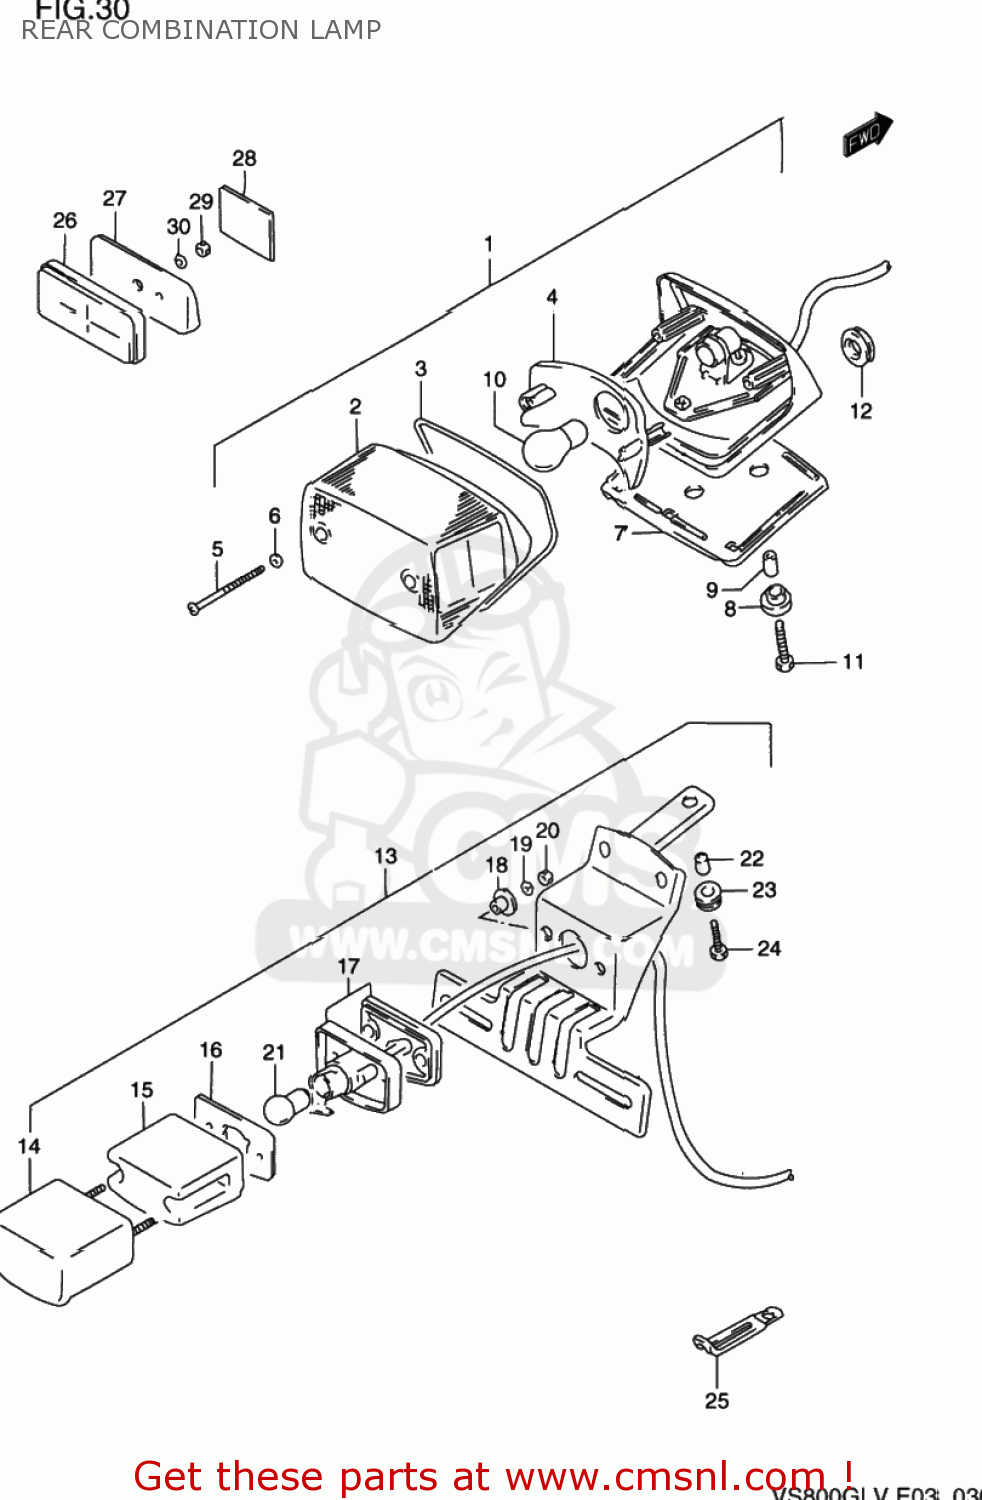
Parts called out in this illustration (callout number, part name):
1	LAMP ASSY,RR COMBINATION
2	LENS
3	GASKET (NAS)
4	REFLECTOR
5	SCREW
6	GASKET (NAS)
7	CUSHION
8	CUSHION
9	SPACER
10	BULB(12V21/5W,BF141-49642A)
11	BOLT 6X25
12	GROMMET
13	LAMP ASSY,LICENSE
14	COVER,LICENSE LAMP
15	LENS
16	GASKET,LICENSE LAMP (NAS)
17	HOUSING,LICENSE LAMP
18	SPACER
19	WASHER,LOCK
20	NUT
21	BULB(12V8W)
22	SPACER
23	CUSHION
24	BOLT
25	CLAMP(L:45)
26	REFLEX REFLECTOR ASSY,RR
27	SPACER
28	TAPE,TOOL BAG PROTECTOR
29	NUT
30	WASHER
